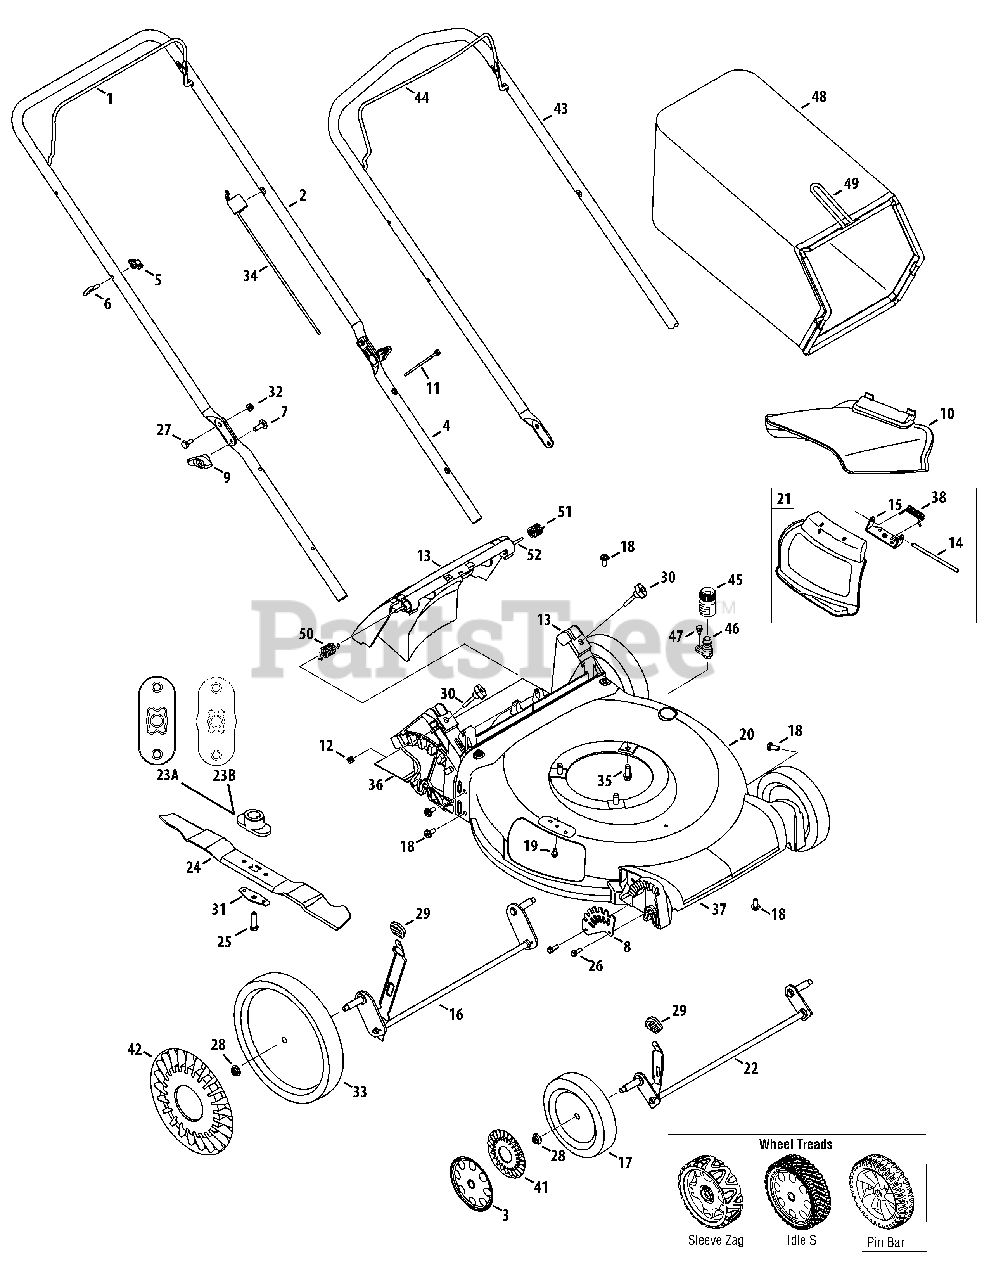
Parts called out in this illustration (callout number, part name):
1	Blade Control Handle - Black
2	Upper Handle - Black (non adjustable)
2	Upper Handle - Black (adjustable)
3	Hub Cap (7")
3	Hub Cap (8")
4	Lower Handle
5	Knob 1/4-20
6	Rope Guide Bolt
7	Carriage Bolt 5/16-18
8	Front Height Adjustment Plate
9	Wing Knob 5/16-18 Red
9	Wing Knob 5/16-18 Black
10	Chute Deflector
10	Chute Deflector (w/clip)
11	Cable Tie
12	Sq. Nut 1/4-20
13	Rear Baffle
14	Hinge Pin
15	Chute Deflector Bracket
16	Rear Axle Ass'y - 8" wheel
17	Wheel Ass'y 7 x 1.8 Pin Bar Grey
17	Wheel Ass'y 7 x 2.0 Sleeve Zag Black
18	Hex Hd. Cap Screw. 5/16-14 x .75
19	Sems TT Screw. 1/4-20 x .50
21	Hinged Mulch Plug Ass'y (Incl. ref. no. 15, 38 & 14)
22	Front Axle Ass'y - 7 " wheel
23A	Blade Adapter
23B	Blade Adapter (25 mm x 1.19)
24	21" Mulching Blade
25	Hex Bolt 3/8-24 x 1.5" Lg. (Gr 8)
26	Screw, 1/4-15 x .750
27	Shoulder Screw .375 x .126 x 1/4-20
28	Flange Locknut 3/8-16 Gr. F Nylon
29	Knob (Black)
29	Knob (Red)
30	Knob 1/4-20 x 1.725 Black
30	Knob 1/4-20 x 1.725 Red
31	Blade Bell Support
32	Flanged Lock Nut 1/4-20 Gr. F Nylon
33	Rear Wheel Ass'y Zag Black
33	Rear Wheel Ass'y Bar Grey
34	Control Cable, 158 cc B&S
34	Control Cable, 160 cc Honda
34	Control Cable, 190 cc B&S
35	Hex Wash HD Tap Screw 3/8-16 x .88
36	Trailing Shield 4.54 x 17.37
37	Front Axle Cover
37	Front Axle Cover (White)
38	Torsion Spring
41	Hub Cap (7")
41	Hub Cap (8")
42	Hub Cap (11")
43	Upper Handle (Ergo)
44	Blade Control Handle
45	Water Nozzle Adapter
46	Deck Water Nozzle
47	Shoulder Screw 1/4-20 x .50
48	Grassbag, Black Std. Mesh
48	Grassbag, Black Dust Blocking
48	Grassbag, White
49	Grassbag Frame
50	Torsion Spring RH
51	Torsion Spring LH
52	Pivot Rod
